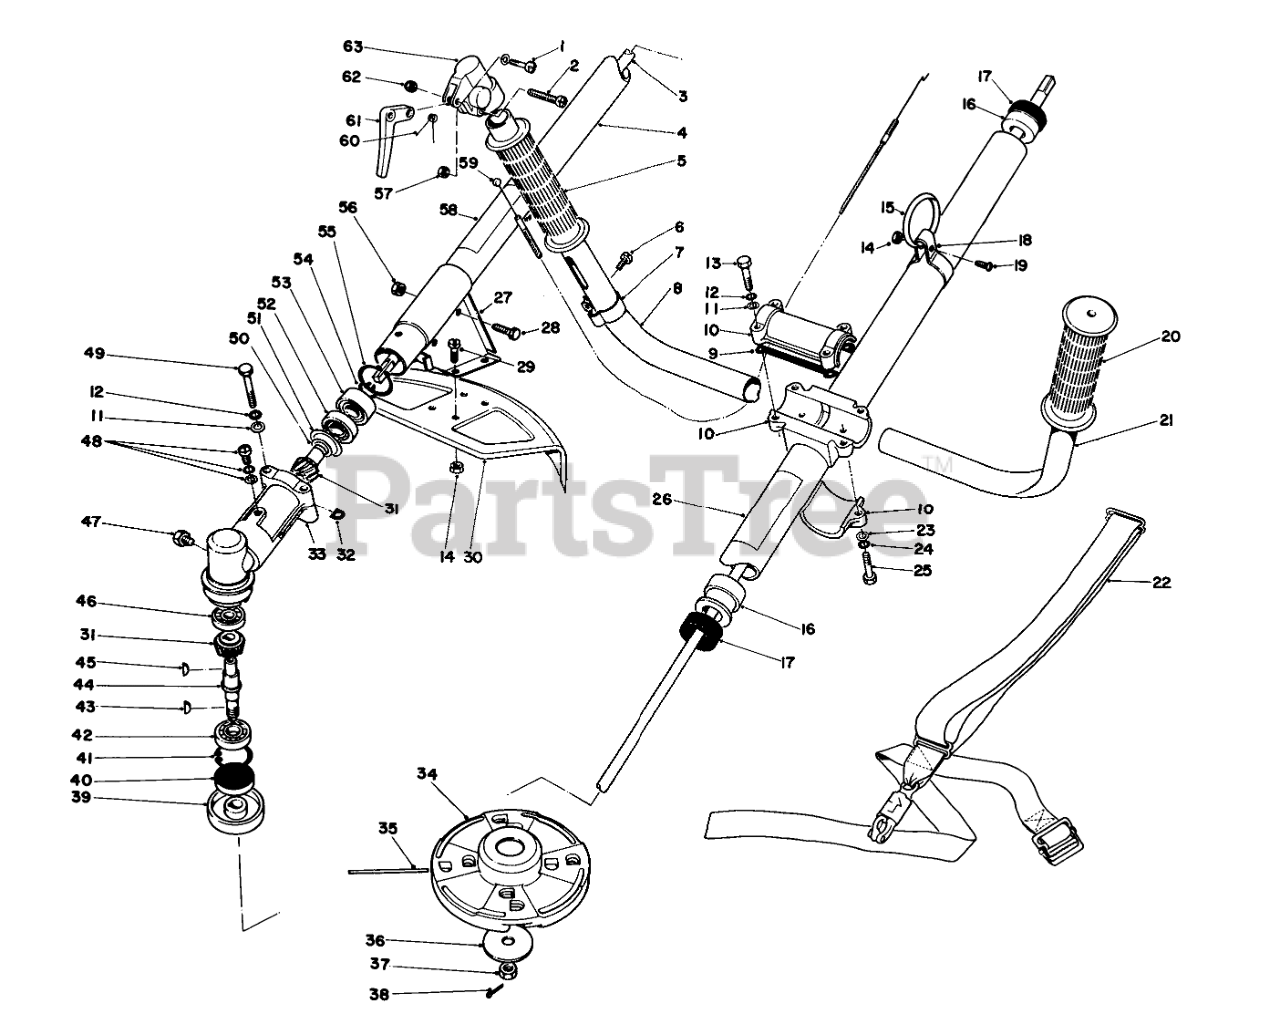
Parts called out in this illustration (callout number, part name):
1	Screw
2	Screw w/Washer
3	Shaft-Driving
4	Housing-Drive Shaft (Incl. Ref. #26 & 27)
5	Right Hand Grip
6	SCREW
8	Handle R.H.
9	Spacer
10	Bracket Assembly-Handle (Incl. Ref. #9-13 & 23-25)
11	WASHER
12	Washer
14	NUT-LOCK, NI
15	RING-HARNESS
17	Bushing
18	HARNESS CLAMP
19	SCREW-SRH
20	LH GRIP
21	Handle L.H.
22	Deluxe Harness
23	Washer
24	Washer
26	Decal
27	Bracket Shield
28	SCREW-HH
29	SCREW-PPH
30	Shield
31	Gear Set
32	Spacer
33	Gear Housing
34	FIXED LINE CUTTER HD PK
35	LINE PACK (100)
36	WASHER
38	1/16 X 1 LG COTTER PIN
39	Plate-Blade Fixing
40	Oilseal
41	Circlip
42	Ball Bearing
43	Woodruff Key
44	Shaft-PTO
45	Woodruff Key
46	Ball Bearing
48	SCREW
50	Washer
51	Washer
52	Ball Bearing
53	Ball Bearing
54	Circlip
55	Circlip
56	NUT-LOCK, NI
57	Nut
58	Decal-TC800
59	Throttle Cable
60	Return Spring
61	THROTTLE LEVER
63	Bracket-Throttle Trigger
